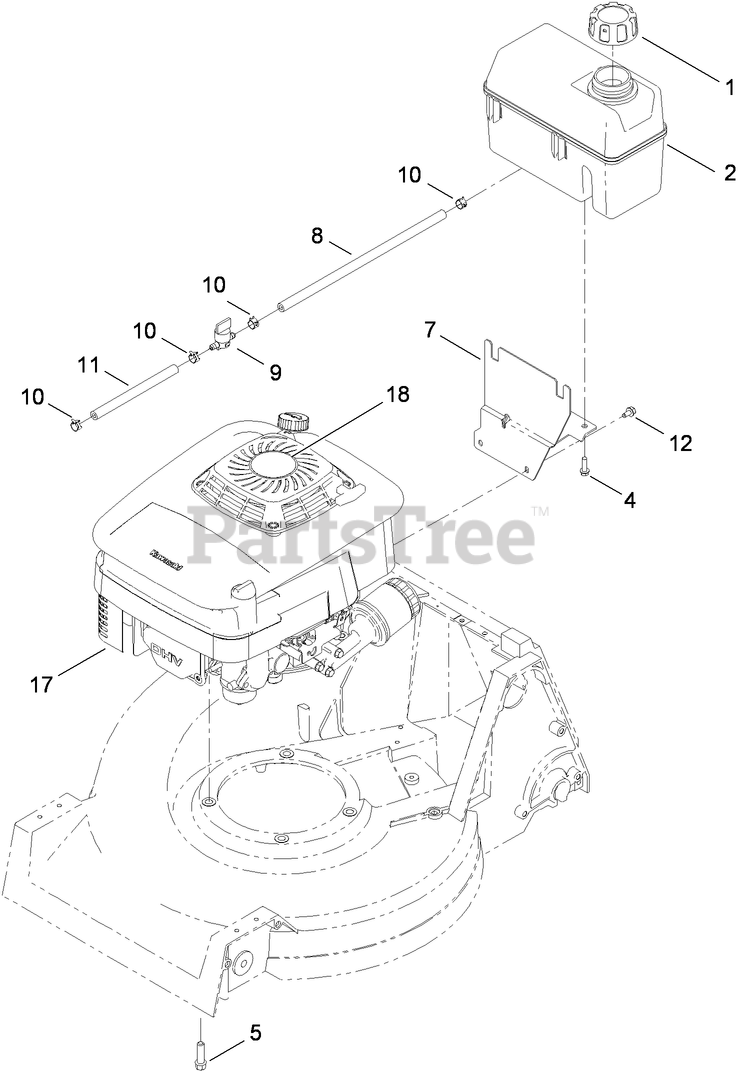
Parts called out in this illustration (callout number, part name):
1	CAP-GAS
2	TANK-FUEL
4	SCREW-HWH
5	SCREW-TAPTITE
7	MOUNT-TANK
8	HOSE-FUEL
9	VALVE-FUEL
10	CLAMP-HOSE
11	HOSE-FUEL
12	SCREW-HWH
17	ENGINE ASM
